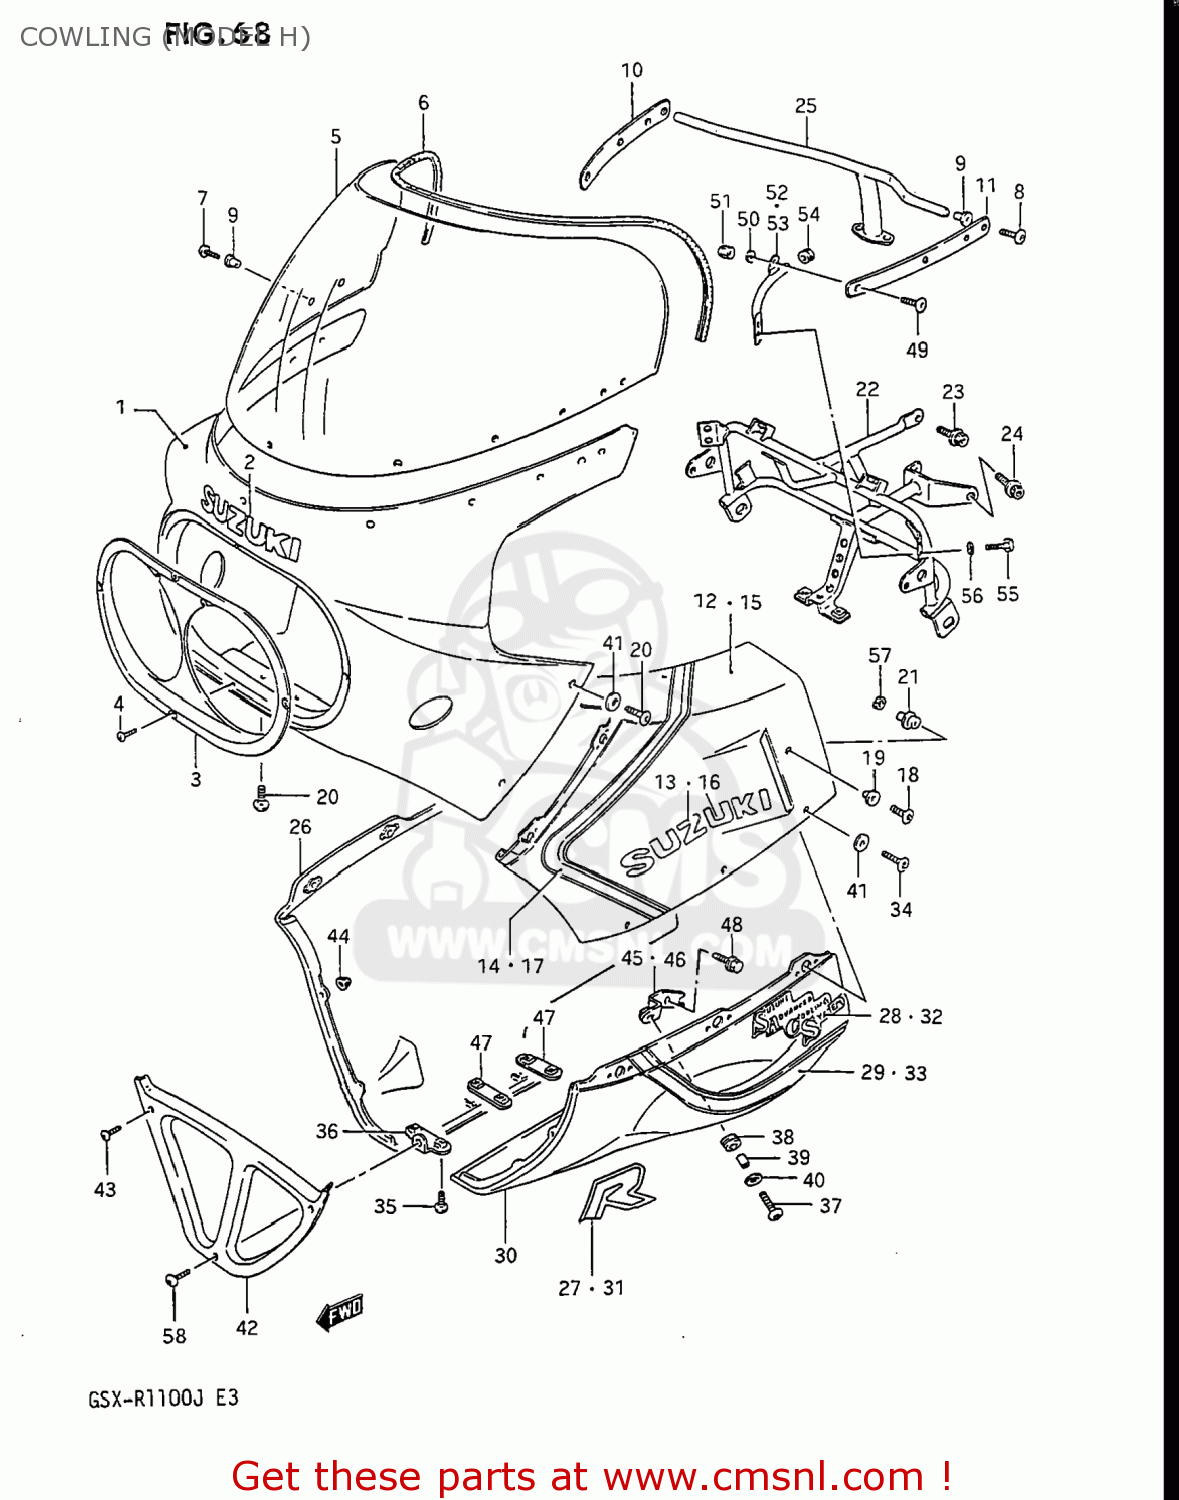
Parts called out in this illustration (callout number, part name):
1	BODY ASSEMBLY,COWLING
2	EMBLEM
3	COVER,COWLING,FRONT
4	SCREW
5	WINDSCREEN
6	MOLDING,SCREEN
7	SCREW(5X14)
8	SCREW(5X18)
9	NUT,COWLING SCREEN
10	PLATE,RR VIEW MIRROR,R
11	PLATE,RR VIEW MIRROR,L
12	COVER COMP,COWLING SIDE,RIGHT
13	EMBLEM
14	TAPE SET,COVER SIDE,RIGHT
15	COVER,COWLING SIDE,LEFT
16	EMBLEM
17	TAPE SET,COVER SIDE,LEFT
18	SCREW(6X12)
19	WASHER
20	SCREW(6X16)
21	CUSHION,COWLING
22	BRACE,COWLING FR
23	BOLT
24	BOLT
25	BRACE,COWLING BODY RR
26	COVER COMP,COWLING,LOWER
27	EMBLEM,COWLING LWR
28	EMBLEM
29	TAPE SET,COWL LWR,R
30	COVER COMP,COWLING,LOWER
31	EMBLEM,COWLING LWR
32	EMBLEM
33	TAPE SET,COWLING,LOWER
34	SCREW(6X16)
35	SCREW(6X16)
36	BRACE,COWLING LWR COVER
37	SCREW(6X20)
38	CUSHION
39	SPACER
40	WASHER(6.5X18X1)
41	WASHER
42	COVER,COWLING,LOWER,FRONT
43	SCREW(5X14)
44	NUT
45	BRACE,COWLING LWR,R
46	BRACE,COWLING LWR,L
47	BRACE,COWLING LWR COVER RR
48	BOLT
49	SCREW(6X16)
50	WASHER,LOCK
51	NUT 6MM
52	BRACE,MIRROR,R
53	BRACE,MIRROR,L
54	PLUG(OD:12)
55	BOLT 6X16
56	WASHER,LOCK
57	WASHER
58	SCREW(6X16)
